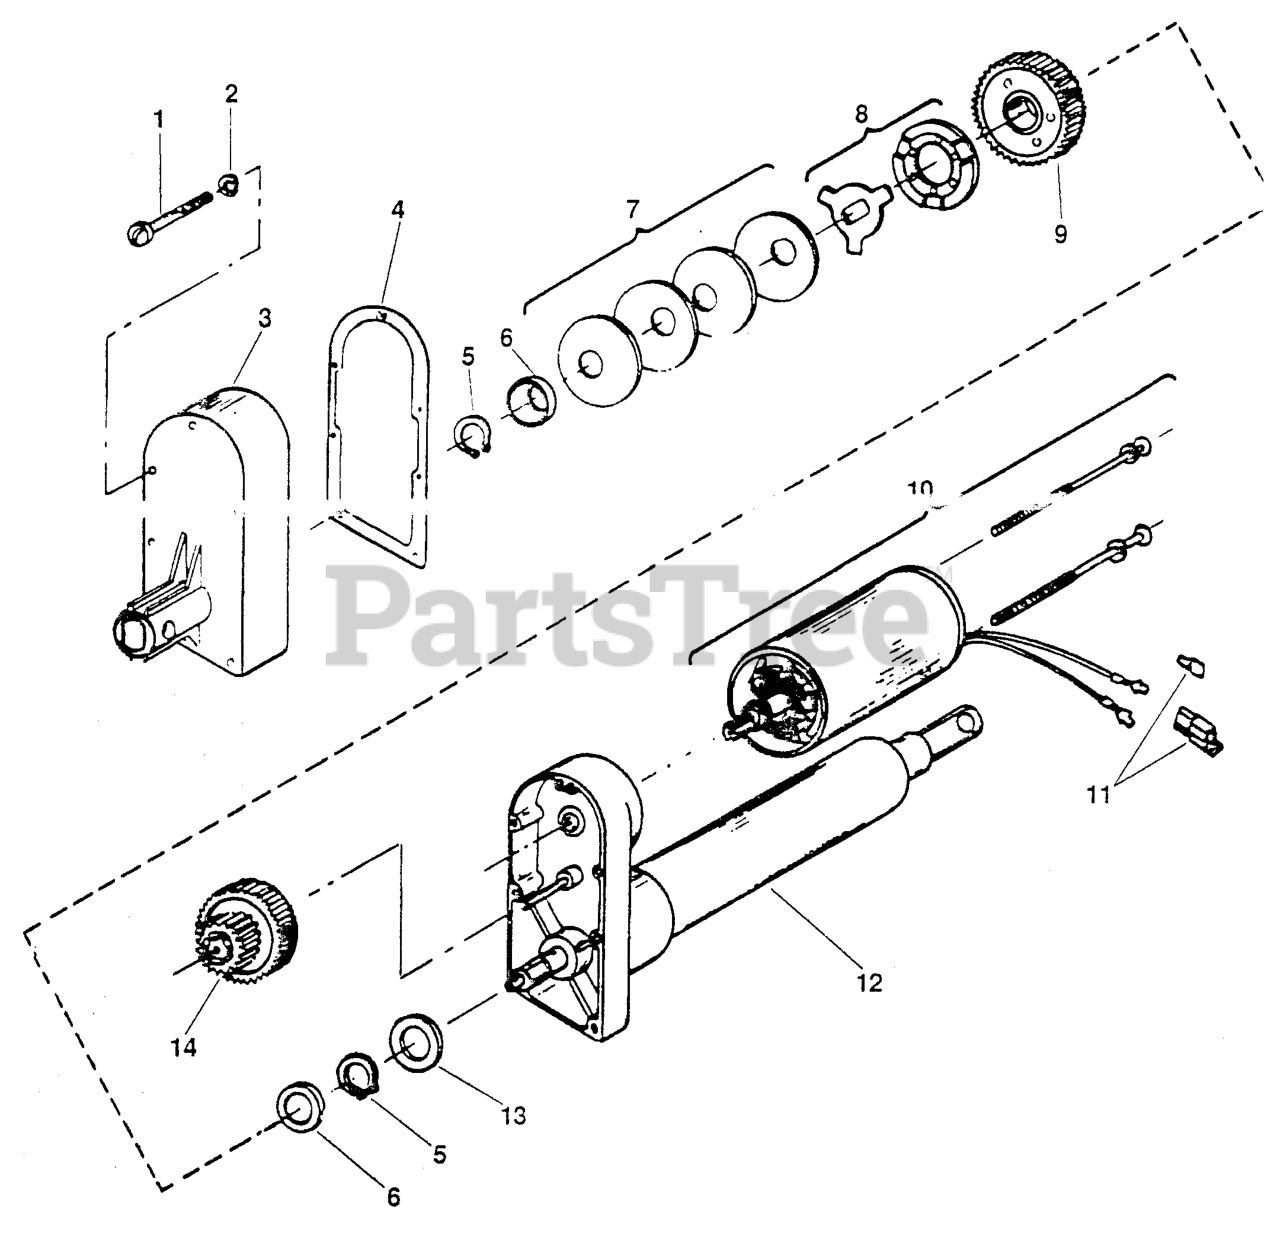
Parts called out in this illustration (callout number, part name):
1	Screw - Sl. Fil. Hd. Mach. No. 10-32 x 1-5/8
2	Lockwasher - No. 10
3	Housing Cover
4	Cover Gasket
5	Snap Ring
6	Retaining Ring
7	Spring Washer
8	Pawl & Ramp Washer
9	Out put Gear
10	Motor - 12V
11	Connector Body Kit
13	Thrust Washer
14	Intermediate Gear
